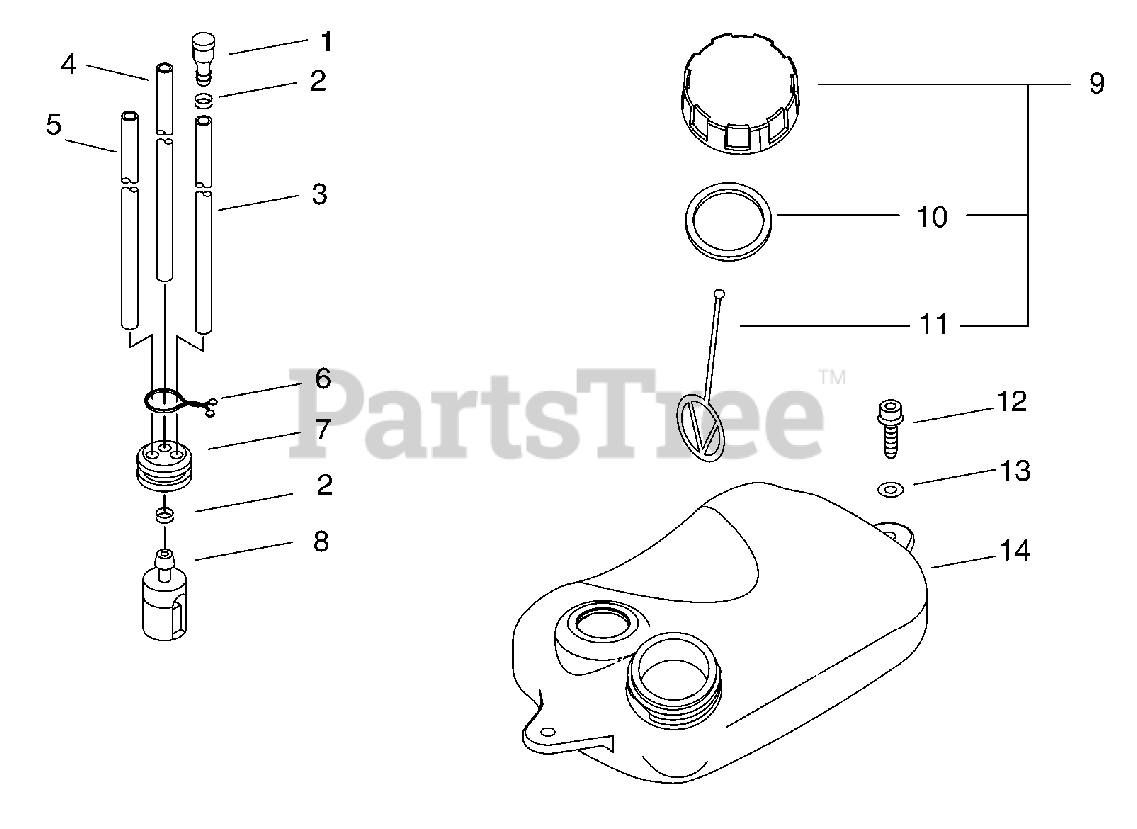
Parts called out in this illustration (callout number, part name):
1	VENT, FUEL TANK
2	CLIP - 6
3	PIPE - 3X5X70 -- BLACK
4	PIPE - 3X5X210 -- BLACK
5	PIPE - 3X6X125 -- CLEAR
7	GROMMET
8	FILTER, FUEL
9	CAP ASSY - ORANGE
10	GASKET, CAP
11	CONNECTOR, CAP
12	SCREW - 5X20
13	WASHER - 5
14	TANK, FUEL
